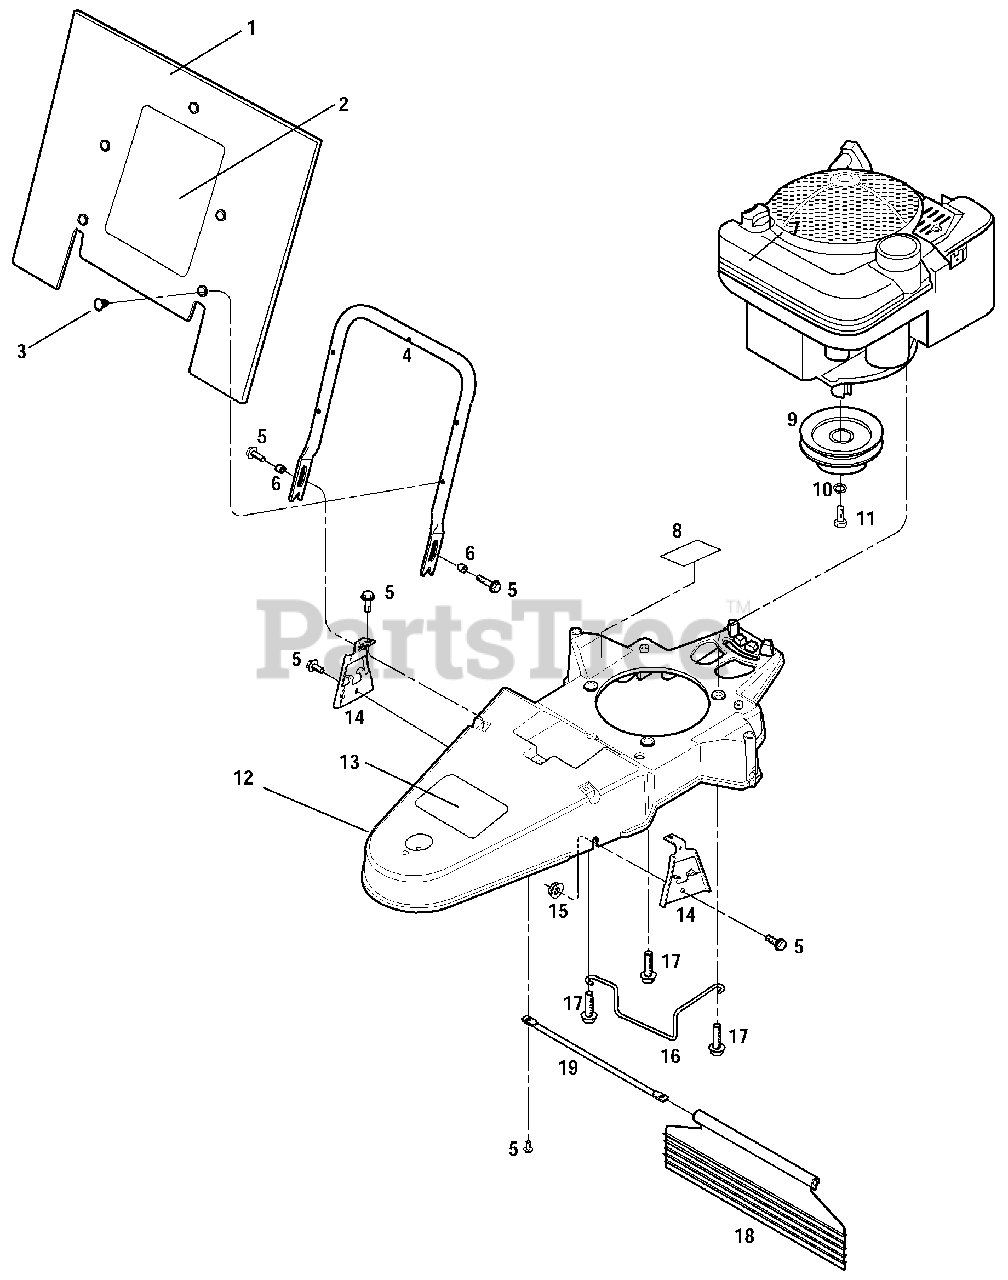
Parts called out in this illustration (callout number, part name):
1	Debris Guard
2	Decal-Logo
3	Push-in Fastener
4	Debris Guard Support
5	Hex Flange Screw, 1/4-20 x 3/4
6	Spacer
7	Engine
8	Decal-Hot Surface Warning
9	Engine Pulley
10	Spring Lock Washer
11	Hex Hd. Screw, 3/8-24 x 1, Grade 5
12	Deck
13	Decal-Warning
14	Hood Bracket
15	Flange Lock Nut, 1/4-20
16	Belt Guide
17	Hex Hd. Screw, 3/8-16 x 1-1/2
18	Deflector Flap
